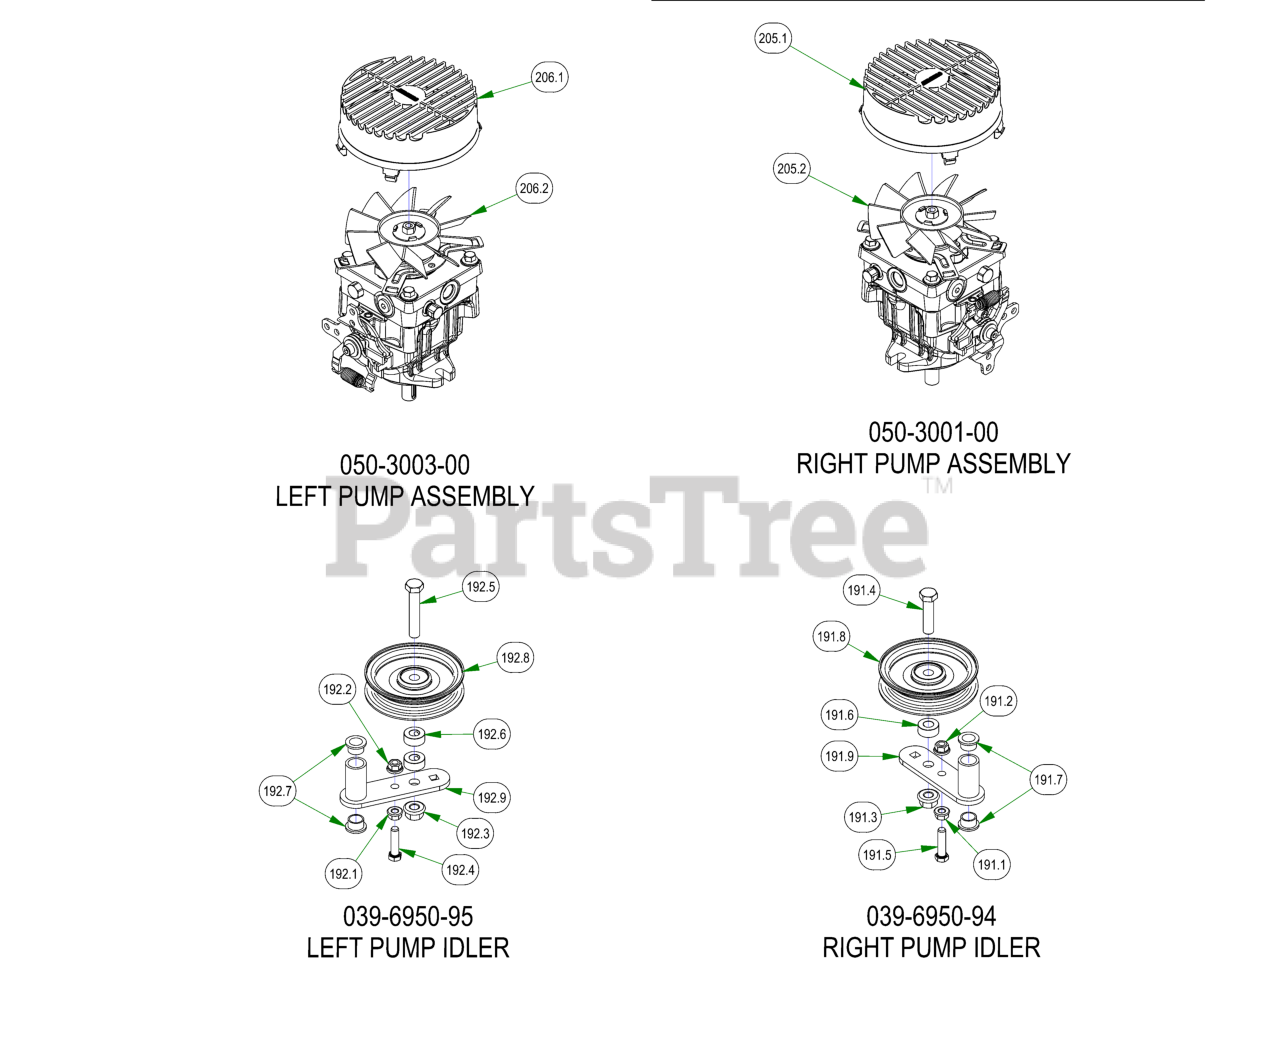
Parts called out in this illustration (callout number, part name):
44	5/16-18 X 2-1/4 HEX CAP SCREW (GR.5) ZINC
128	.380 ID X .625 OD X 1.500 LGTH 2019 OUTLAW BRAKE HANDLE
168.1	5" Pump Pulley
168.2	5/16-24 X 1/2 SOCKET SET SCREW KNURLED CUP POINT
191	2020 Diesel Pump Tensioner Assembly LH
191.1	3/8-16 HEX SERRATED FLANGE NUT HARD/ZINC
191.2	3/8-16 NYLON INSERT FLANGE LOCKNUT (GR.F) ZINC
191.3	1/2-13 NYLON INSERT FLANGE LOCKNUT ZINC
191.4	1/2-13 X 2 HEX CAP SCREW (GR.8) ZINC YELLOW
191.5	3/8-16 X 1-1/2 HEX CAP SCREW (GR.5) ZINC
191.6	1/2 SOLID SHAFT COLLAR (W/1 SET SCREW) ZINC
191.7	.627 ID X .753 OD X .500 LGTH X 1.000 FLG OD X .094 FLG THICK
191.8	4 3/4" Idler Pulley
191.9	Renegade - Gas Pump Idler - Weldment
192	2020 Diesel Pump Tensioner Assembly RH
192.1	3/8-16 HEX SERRATED FLANGE NUT HARD/ZINC
192.2	3/8-16 NYLON INSERT FLANGE LOCKNUT (GR.F) ZINC
192.3	1/2-13 NYLON INSERT FLANGE LOCKNUT ZINC
192.4	3/8-16 X 1-1/2 HEX CAP SCREW (GR.5) ZINC
192.5	1/2-13 X 2-3/4 HEX CAP SCREW (GR.5) ZINC
192.6	1/2 SOLID SHAFT COLLAR (W/1 SET SCREW) ZINC
192.7	.627 ID X .753 OD X .500 LGTH X 1.000 FLG OD X .094 FLG THICK
192.8	4 3/4" Idler Pulley
192.9	Renegade - Gas Pump Idler - Weldment
205	2019 Rogue/Renegade Left Pump 16cc
205.1	Fan Guard 6" - Fits Wheel
205.2	Hydro Fan - Light/Pup/Outlaw XP
206	2019 Outlaw Renegade Right Pump 16cc
206.1	Fan Guard 6" - Fits Wheel
206.2	Hydro Fan - Light/Pup/Outlaw XP
